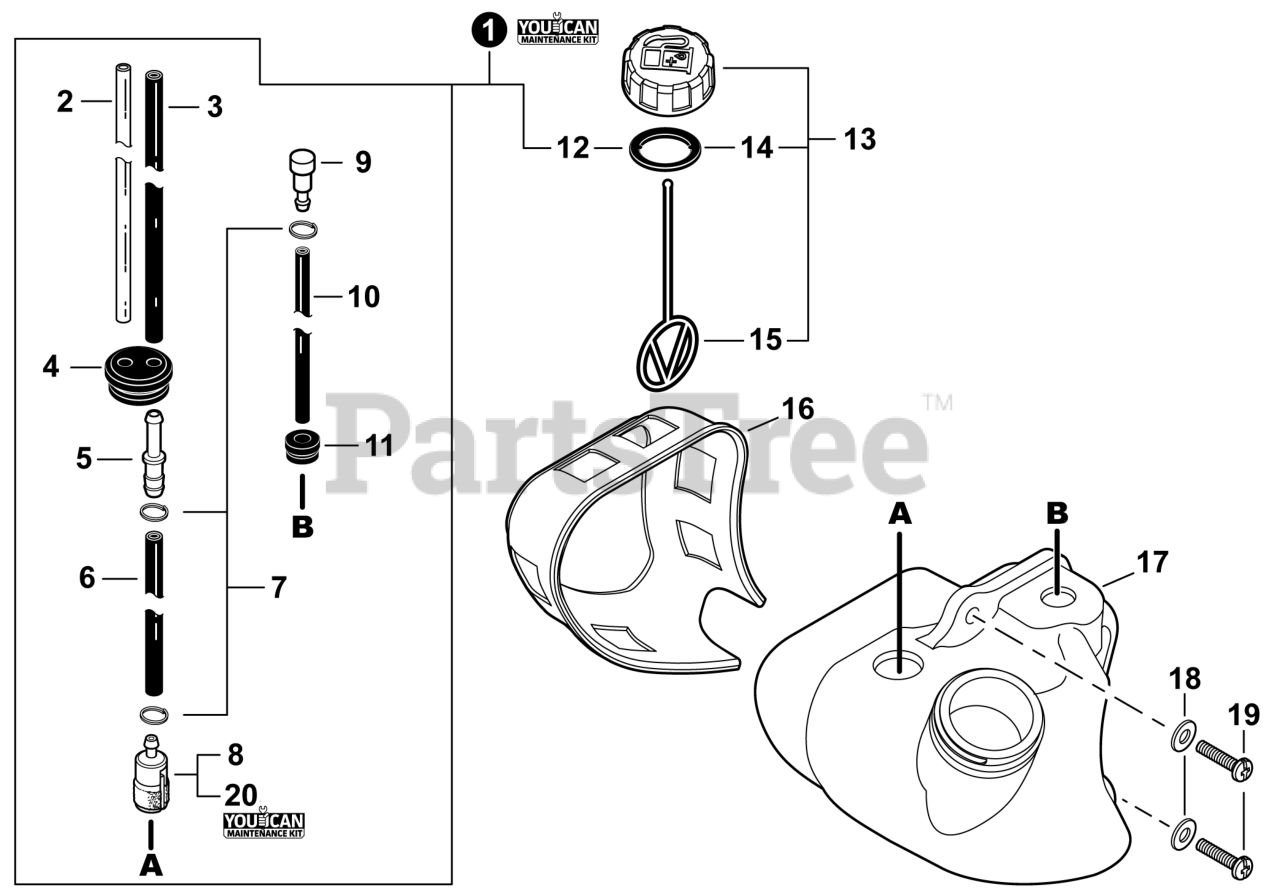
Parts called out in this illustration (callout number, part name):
1	FUEL SYSTEM KIT - YOUCAN™
2	PIPE, FUEL 3x6x85 YELLOW
3	PIPE, FUEL 3x5.5x87 BLACK
4	GROMMET, FUEL
5	CONNECTOR, PIPE 5x3.5
6	PIPE, FUEL 3x5x90 BLACK
7	CLIP 6
8	FILTER, FUEL
9	VENT ASSY
10	PIPE, FUEL VENT 3x5x50
11	GROMMET
12	GASKET, FUEL CAP
13	CAP ASSY, FUEL
14	GASKET, FUEL CAP
15	CONNECTOR, CAP L= 100 MM
16	GUARD, FUEL TANK
17	TANK, FUEL
18	WASHER 5.5x12x0.8
19	SCREW, TAPPING 5x20
20	TUNE-UP KIT - YOUCAN™
